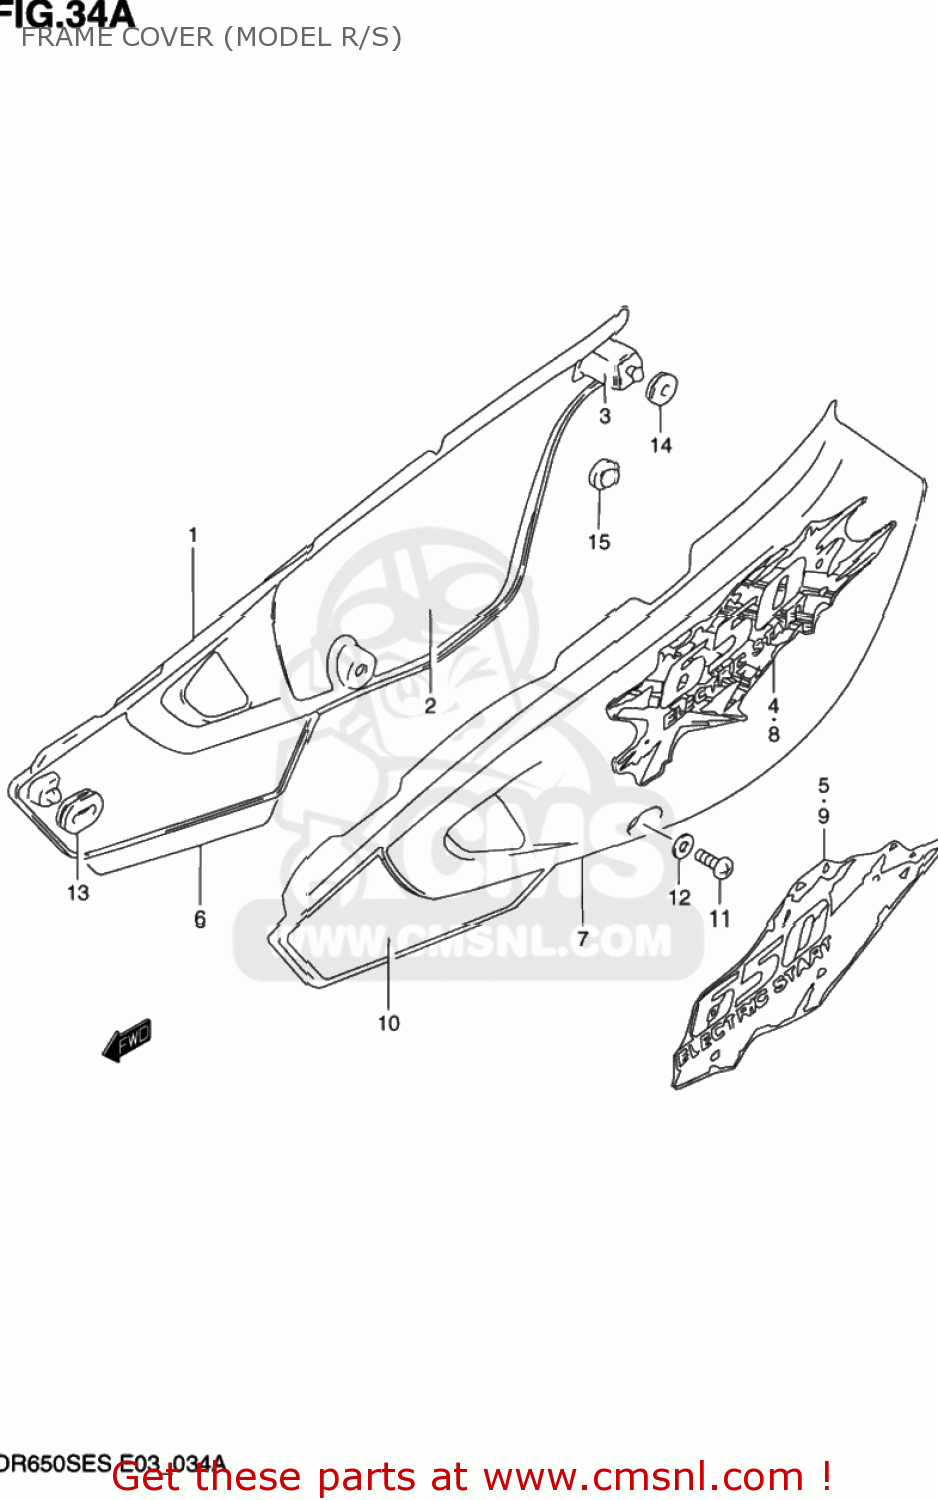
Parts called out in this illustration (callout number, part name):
1	COVER,FRAME,RIGHT
2	SHIELD,FRAME COVER,R
3	SHIELD,FRAME COVER,R NO.2
4	EMBLEM,FRAME COVER
5	TAPE,FRAME COVER,RIGHT
6	TAPE,FRAME COVER NO.2
7	COVER,FRAME,L(WHITE)
8	EMBLEM,FRAME COVER
9	TAPE,FRAME COVER,LEFT
10	TAPE,FRAME COVER NO.2
11	SCREW
12	WASHER
13	CUSHION
14	CUSHION
15	CUSHION
